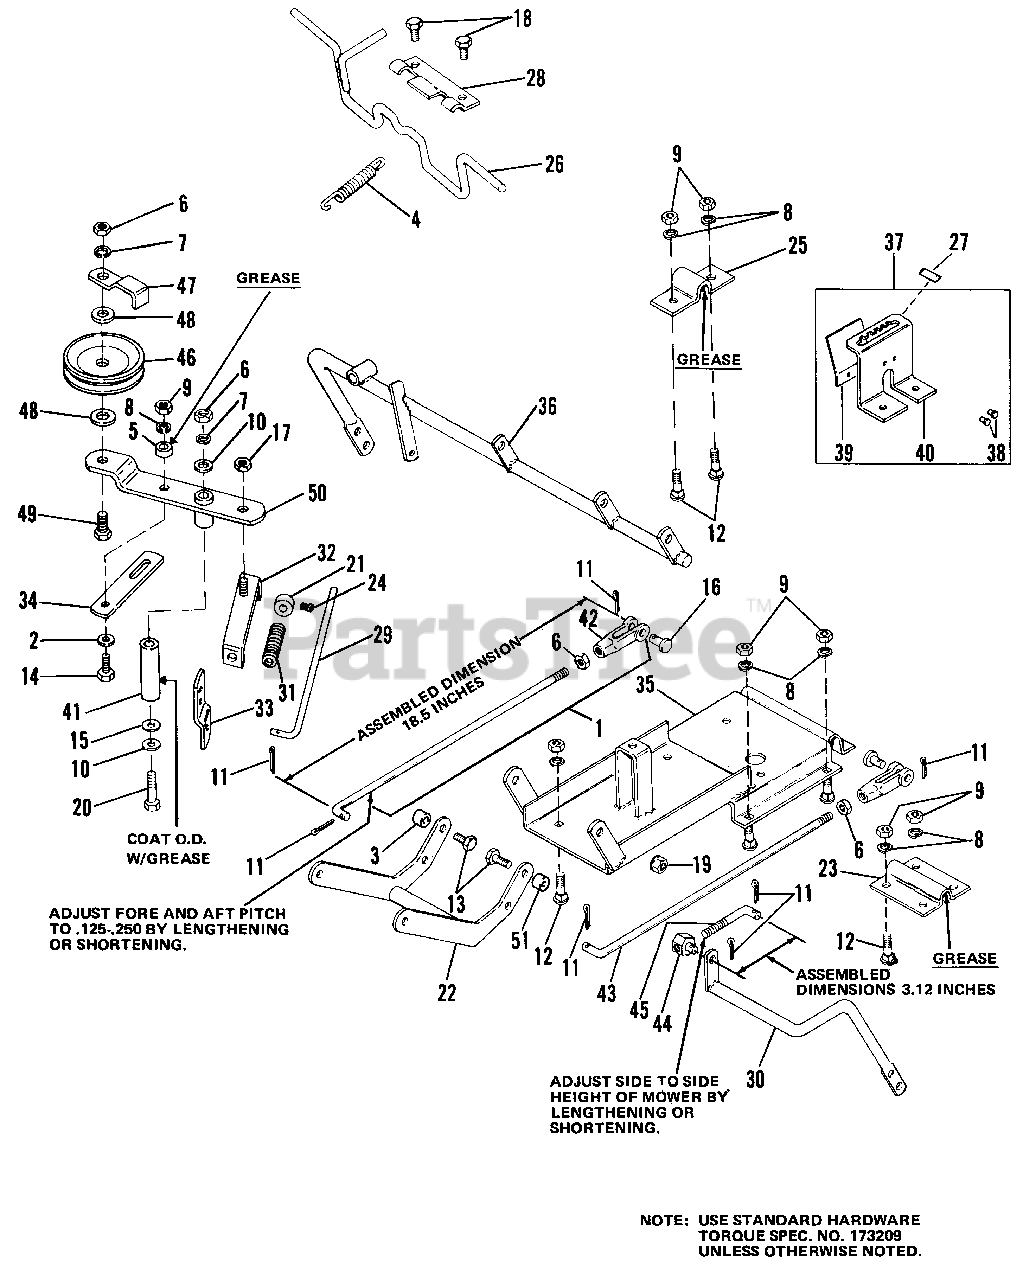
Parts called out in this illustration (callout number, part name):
1	ROD ASSY, Height Adjusting (Includes Ref. No. 6. 42, & 43)
6	NUT, Hex, 3/8-16
7	LOCKWASHER, 3/8
8	LOCKWASHER, 5/16
9	NUT, Hex, 5/16-18
10	WASHER, Plain, 3/8
11	PIN, Cotter, 3/32 x 3/4
12	BOLT, Carriage, Sht Nk., 5/16 x 3/4
13	CAPSCREW, Hex Hd., 3/8-16 x 1
14	CAPSCREW, Hex Hd, 5/16-18 x 1
15	WASHER
16	PIN, Yoke, 3/8
17	LOCKNUT, Hex, 5/16-18
18	SCREW, Washer Hd., Taptite, 1/4-20 x 3/8
19	NUT, Flange, 3/8-16
20	CAPSCREW, Hex Hd., 3/8-16 x 2-1/2 Gr. 8
21	COLLAR, Set
22	ROCKER ARM ASSY
23	CLAMP, Wheel Support
24	SETSCREW, Sq. Hd., Cup Pt., 1/4-20 x 3/8
26	ROD ASSY, Brake
27	DECAL, Mower Height
28	SUPPORT, Brake
30	SUPPORT ASSY, L.H. Roller
34	LEVER, Brake
35	SUPPORT ASSY, Mower
36	SUPPORT ASSY, R.H. Roller
37	QUADRANT ASSY
39	SPRING, Mower Control
43	ROD, Height Adjustment
46	PULLEY, Idler
47	BELT GUIDE
48	WASHER, Plain, 5/16
49	CAPSCREW, Hex Hd., 3/8-16 x 1-1/2
50	LEVER, Clutch
